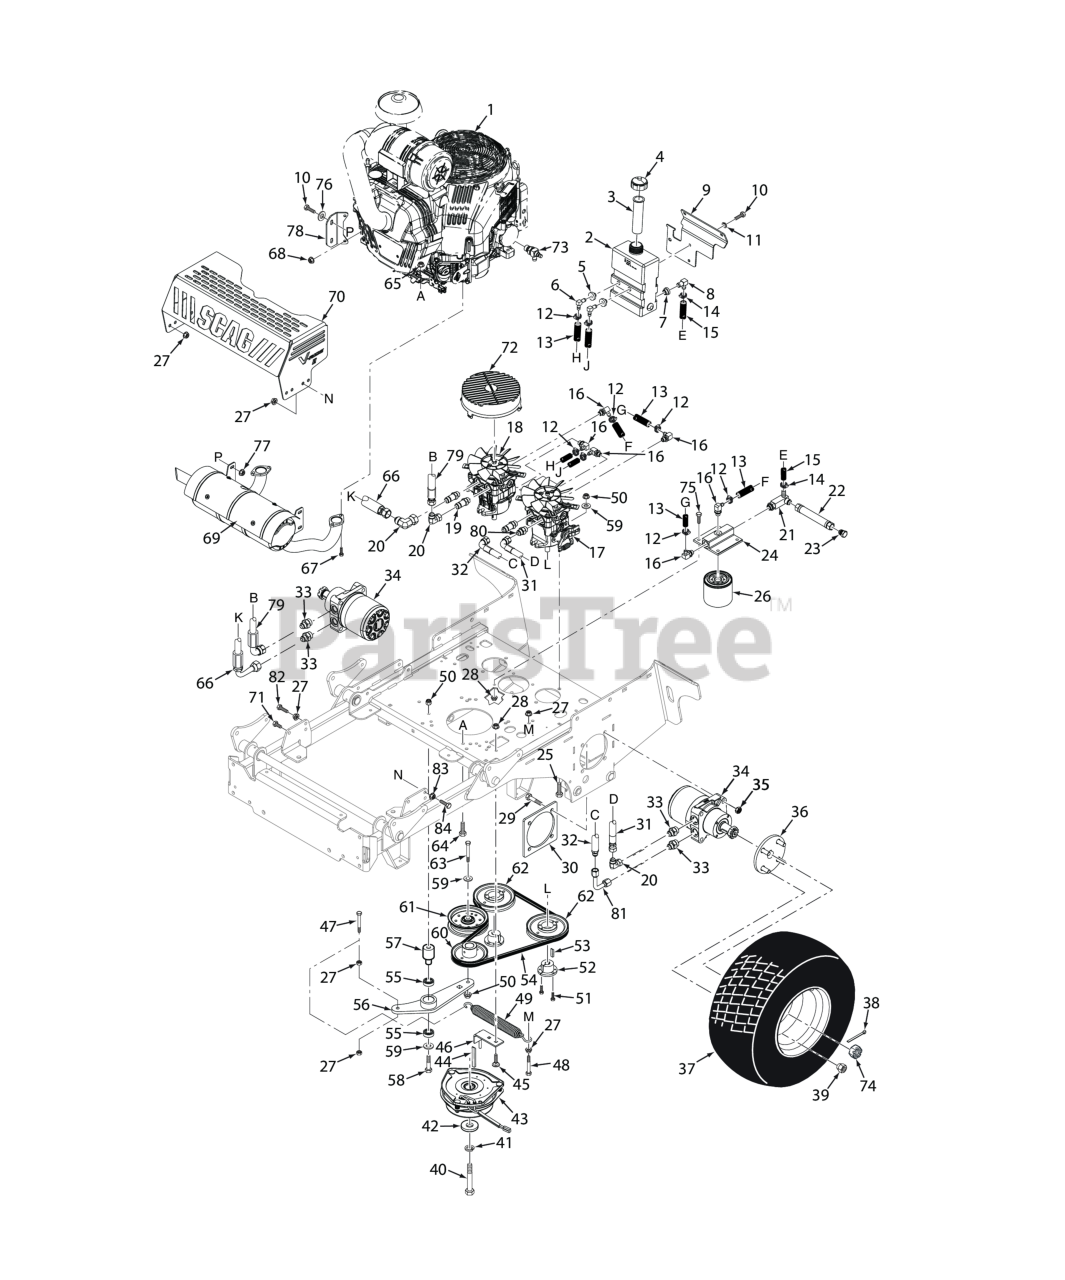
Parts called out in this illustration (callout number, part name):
1	Engine, 40 HP Vanguard EFI
2	Hydro Tank Assy., SVRII
3	Insert, Filler Neck
4	CAP, HYDRAULIC TANK
5	Bushing, 0.56" Dia. Viton
6	Elbow, 90 Degree, 9/16-18 JIC x 9/16 O-Ring
7	Bushing, 0.78" Dia. Viton
8	Fitting, 90 Degree - 1/2" Hose
9	Bracket, Hydro Tank Mounting
10	BOLT, SERRATED FLANGE HEX HEAD 5/16-18 X 3/4"
11	Lockwasher, 5/16 (.317 x .586 x .078) Helical Spring
12	Clamp, .69" Max. / .25" Min. Dia.
13	Hose, 3/8" ID - 10-1/4" Long (Order By The Inch)
14	Clamp, Cable 3/4" I.D.
15	Hose Assembly, 1/2" ID (Oil Reservoir to Filter Base)
16	Elbow, 90 Degree - 9/16" O-Ring x 3/8" Hose
17	Pump, LH - SVRII
18	Pump, RH - SVRII
19	Union, O-Ring to JIC
20	Elbow, 1/2 JIC Female to 1/2 JIC Male
21	Tee, 3/4" O-Ring
22	Drain, Hose Assembly
23	Plug, JIC 3/4-16 UNF
24	Filter Head Assembly
25	Bolt, Hex Head 3/8-16 x 1-1/2" B&S 32BV
26	OIL FILTER, SPECIAL
27	NUT, 3/8-16 SERRATED FLANGE HEX HEAD
28	Nut, Serrated Flange 5/16-18 (Right Front Engine Mounting, Briggs and Kohler Only)
29	Bolt, Hex Hd. 1/2-13 x 2-1/2" (lower)
30	Plate Weldment, Motor Backing
31	Hose Assembly
32	Hose Assy., 18-1/2"
33	TUBE UNION, 3/4-16 JIC TO 7/8-14 "O" RING
34	Wheel Motor, Parker
35	Locknut, Hex 1/2-13 Center Lock
36	Wheel Hub Assy., SVRII
37	Wheel Assembly, 24 x 12-12 (SPZ61)
38	Pin, Cotter 9/16" x 1-1/2"
39	Wheel Nut, 1/2-20 x 13/16
40	Bolt, Hex Head 7/16-20 x 2-1/4" w/Patch (Kawasaki)
41	Lockwasher, 7/16� Spring
42	Flatwasher, 7/16-.469 x 1.75 x .25 (48, 52)
43	Clutch w/Tag GT3.5--FE05 (61)
44	Key, 1/4 x 1/4 x 3-1/2"
45	Bolt, 5/16-18 x .75 RHSN Carriage
46	ANTI-ROTATION WLMT, SVRII
47	Bolt, Hex Head 3/8-16 x 1-1/2" Grade 8 Black
48	Bolt, Hex Head 3/8-16 x 3" - 52"
49	Spring, Transmission Drive
50	HEX NUT, ELASTIC STOP LOCK, 3/8-16
51	Bolt, Hex Head 1/4-20 x 1" Grade 8 Black
52	Hub, Tapered, 15mm Bore
53	KEY, 5 MM X 5 MM X 25 MM
54	Belt, Pump Drive (37BV-EFI)
55	BEARINGS, BALL, NEUTRAL RETURN
56	Idler Arm Assy.
57	Pivot, Idler
58	Capscrew, Hex Head 3/8-16 x 3.25"
59	Flatwasher, 3/8 (.391 x .938 x .105 HD) Grade 8
60	Pulley, 4-3/4" OD - 1.125 Bore
61	Pulley, Idler 4-1/2"
62	Pulley, 5.45 OD - Tapered Bore"
63	Bolt, Hex Head 3/8-16 x 2-1/4" - 61"
64	Bolt, Hex Head 3/8-16 x 1-1/2" B&S 32BV
65	Nut, Flanged Top Lock 3/8-16
66	Hose Assy., 15-1/4"
67	Bolt, Hex Head M8 - 1.25 x 20
68	Nut, M6-1.0 Hex Flange
69	Muffler, Vanguard 37 EFI - SVRII
70	Heatshield, Muffler- SVRII
71	Bolt, Hex Head, 3/8-16 x 3/4"
72	Fan Cover, Pump
73	Oil Drain, 35BV & 37BV-EFI - Briggs & Stratton
74	Nut, Hex Castle 1.0-20 UNEF
75	Bolt, Heax Head 5/16-18 x 1" (48V / 52V)
76	Flatwasher, 5/16-.375 x .875 x .083 (35BV & 37BV-EFI)
77	Nut, Flange Head Elastic Stop 5/16-18
78	Bracket, Muffler Mount
79	Hose Assy., 27-1/2"
80	Union, 3/4"-16 JIC x 3/4"-16 O-Ring
81	Tube Assy.
82	Bolt, Hex Head 3/8-16 x 1-1/2" Grade 8 Black
83	NUT, 3/8-16 SERRATED FLANGE HEX HEAD
84	Bolt, Hex Head 3/8-16 x 1-1/2" Grade 8 Black
